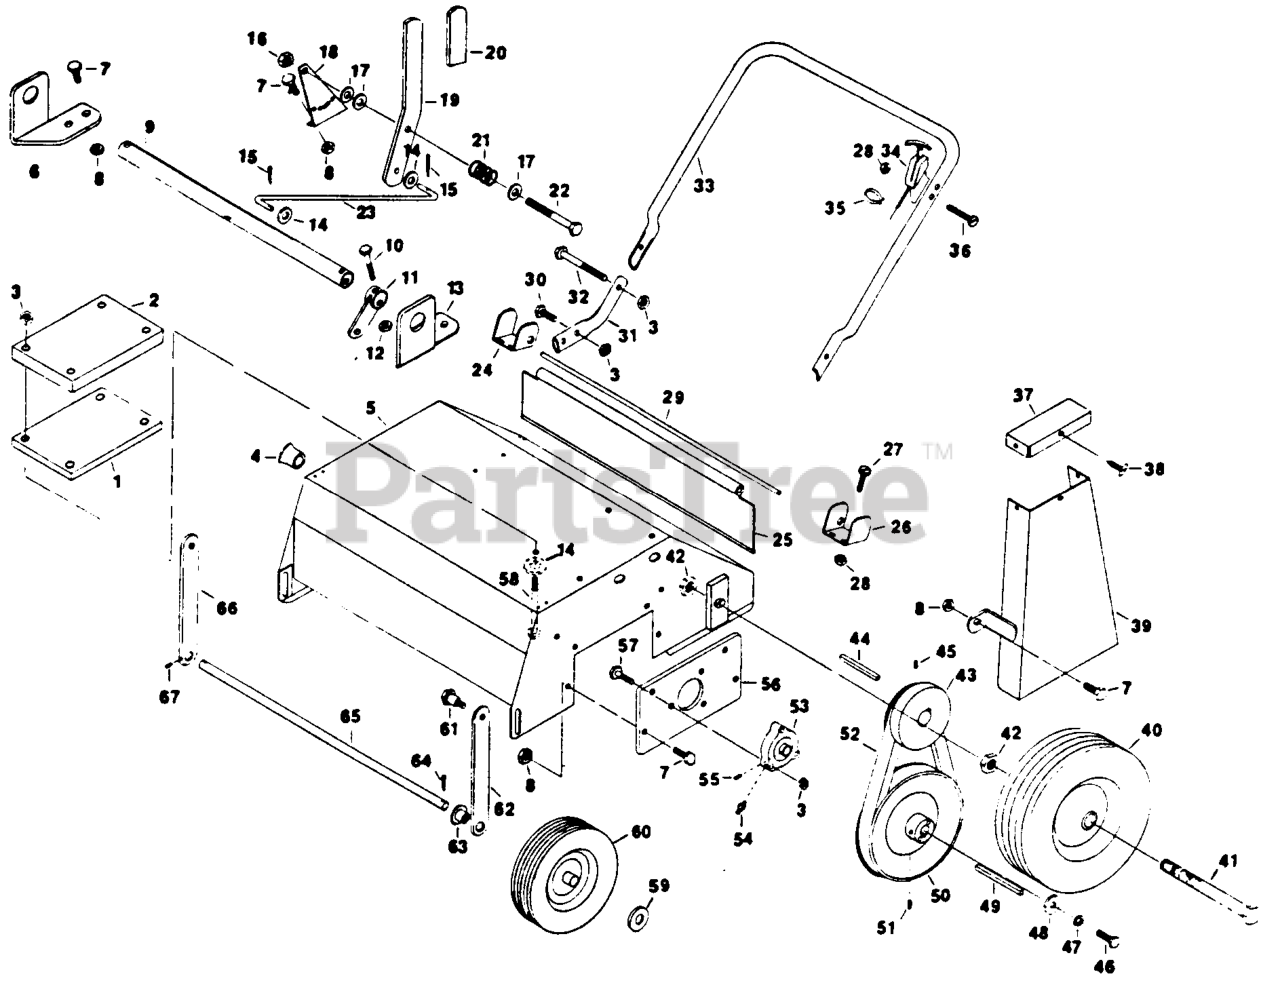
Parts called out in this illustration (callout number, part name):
12	NUTTORQUE ZNKPLT
15	PIN-COTTER
20	GRIP-LEVER
21	SPRING-COMPRESSION
40	ASM,WHEEL & TIRE
47	WASHER-LOCK
48	WASHER-RETAINER, PULLEY
51	SCREW-SET
52	BELT,RAKE
60	ASM,WHEEL & TIRE
